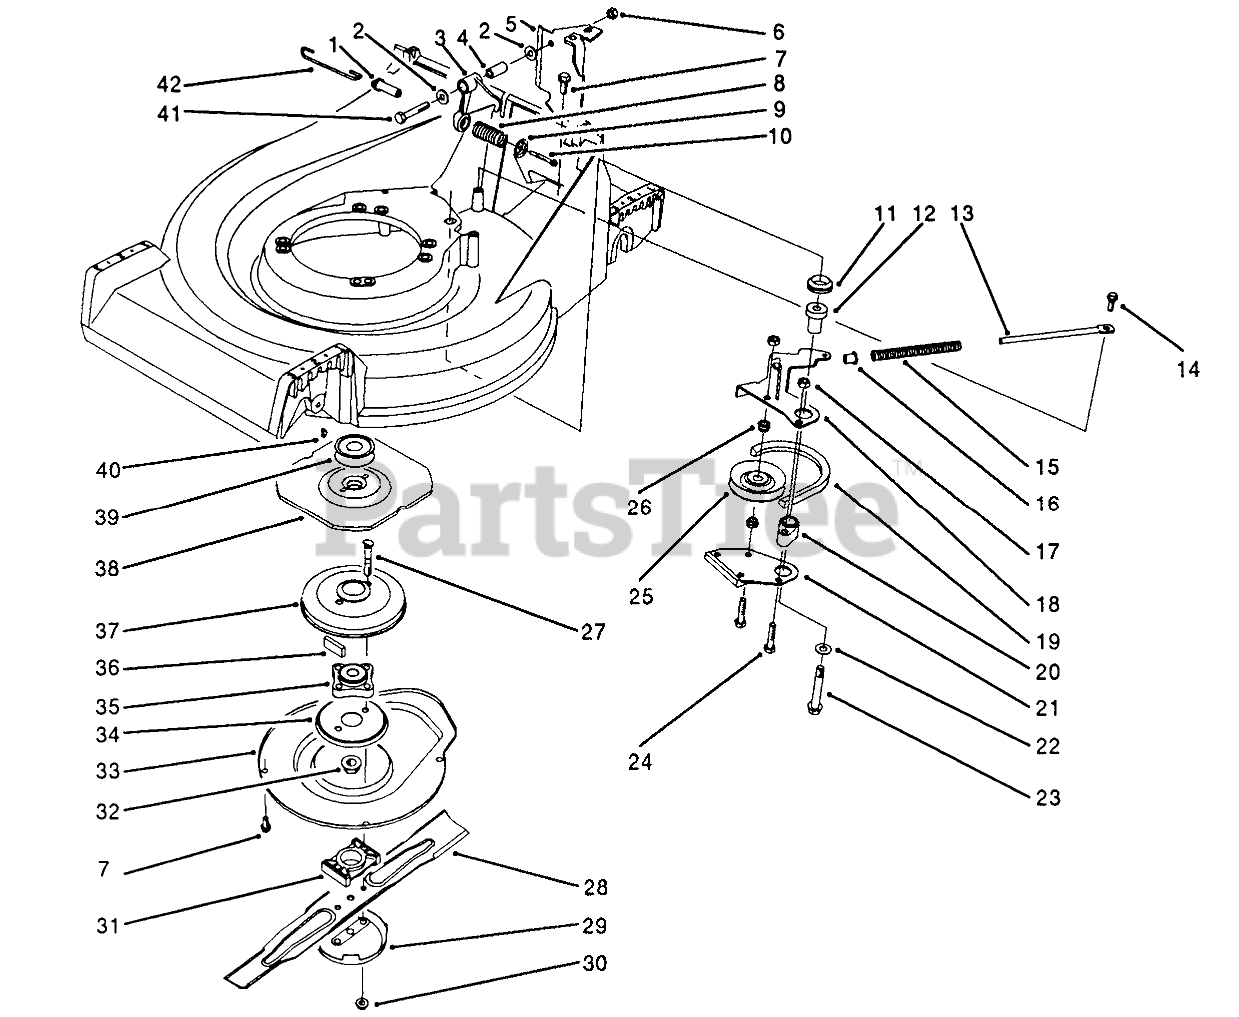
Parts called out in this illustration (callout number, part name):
1	SPRING PIN
2	WASHER-PLAIN
3	CRANK
4	STRAIGHT BUSHING
5	Bracket-Cable Support
7	SCREW-HWHTF
8	COMPRESSION SPRING
9	RETAINER-SPRING
10	SCREW-HWHTF
11	V-RING SEAL
12	BBC PM BUSHING
13	SPRING ROD
14	SCREW-SHOULDER
15	COMPRESSION SPRING
16	SPACER
17	NUT-LOCK, NI
18	Lever
19	V-BELT
20	BRAKE PLATE HUB
21	BRAKE SHOE
22	WASHER-PLAIN
23	3/8-16 X 2-3/4 CAPSCR
24	SCREW-HH
25	PULLEY-IDLER
26	IDLER PULLEY HUB
27	BOLT-BLADE
28	Key
29	CUP-SCALP, ANTI
30	NUT-LOCK
31	SPACER-BLADE
32	NUT-LOCK, NI
33	Cover
34	Screen-BBC
35	HUB ASM
36	DAMPENER-VIBRATION
37	BRAKE DRUM
38	FLYWHEEL - BBC
39	PULLEY
40	KEY-WOODRUFF
41	SCREW-HH
42	CONTROL LINK
